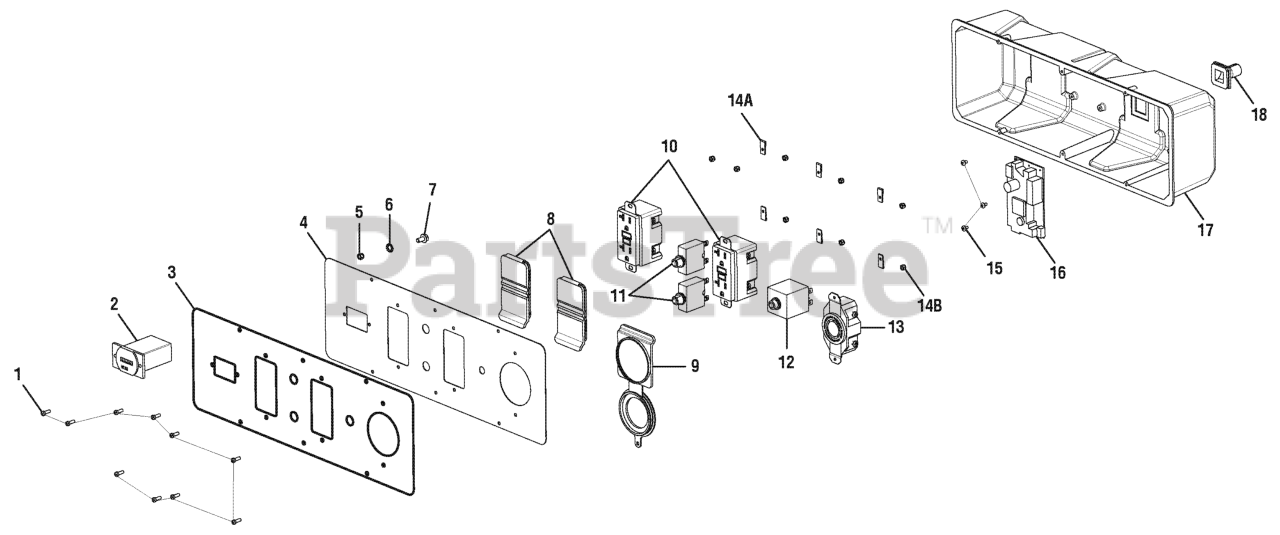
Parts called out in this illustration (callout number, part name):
1	SCREW (6-20 X 3/8 IN.)
2	HOUR METER (120 VOLT)
3	LABEL (POWER OUTLET)
4	FRONT PANEL
5	LOCK NUT (M4)
6	STAR WASHER (ID6.4XOD11X0.6T)
7	BOLT (M5 X 10 MM)
8	OUTLET COVER (120 VOLT)
9	OUTLET COVER (240 VOLT)
10	120 VOLT DUPLEX RECEPTACLE
11	CIRCUIT BREAKER 20AMP, 125VOLT
12	CIRCUIT BREAKER (30 AMP)
13	TWST LCK RECEPT 120/240VLT 30A
14B	LOCK NUT
15	SCREW (M3 X 5 MM)
16	CIRCUIT BOARD
17	CONTROL BOX (BACK PANEL)
18	RUBBER BOOT
